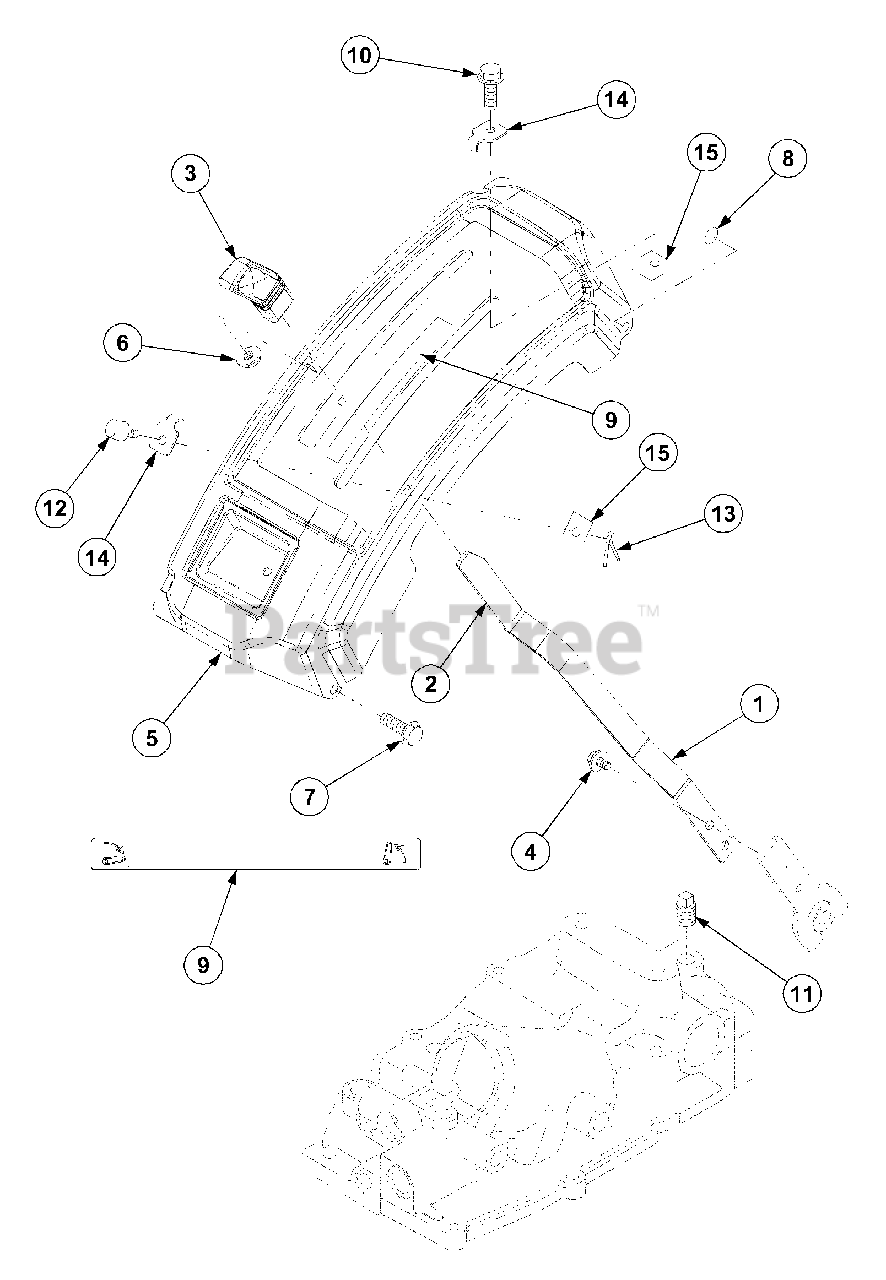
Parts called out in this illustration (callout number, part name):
4	Bolt,w/Washer
5	Lever Guide RH
7	Bolt,w/Washer
15	Plate,Stopper
